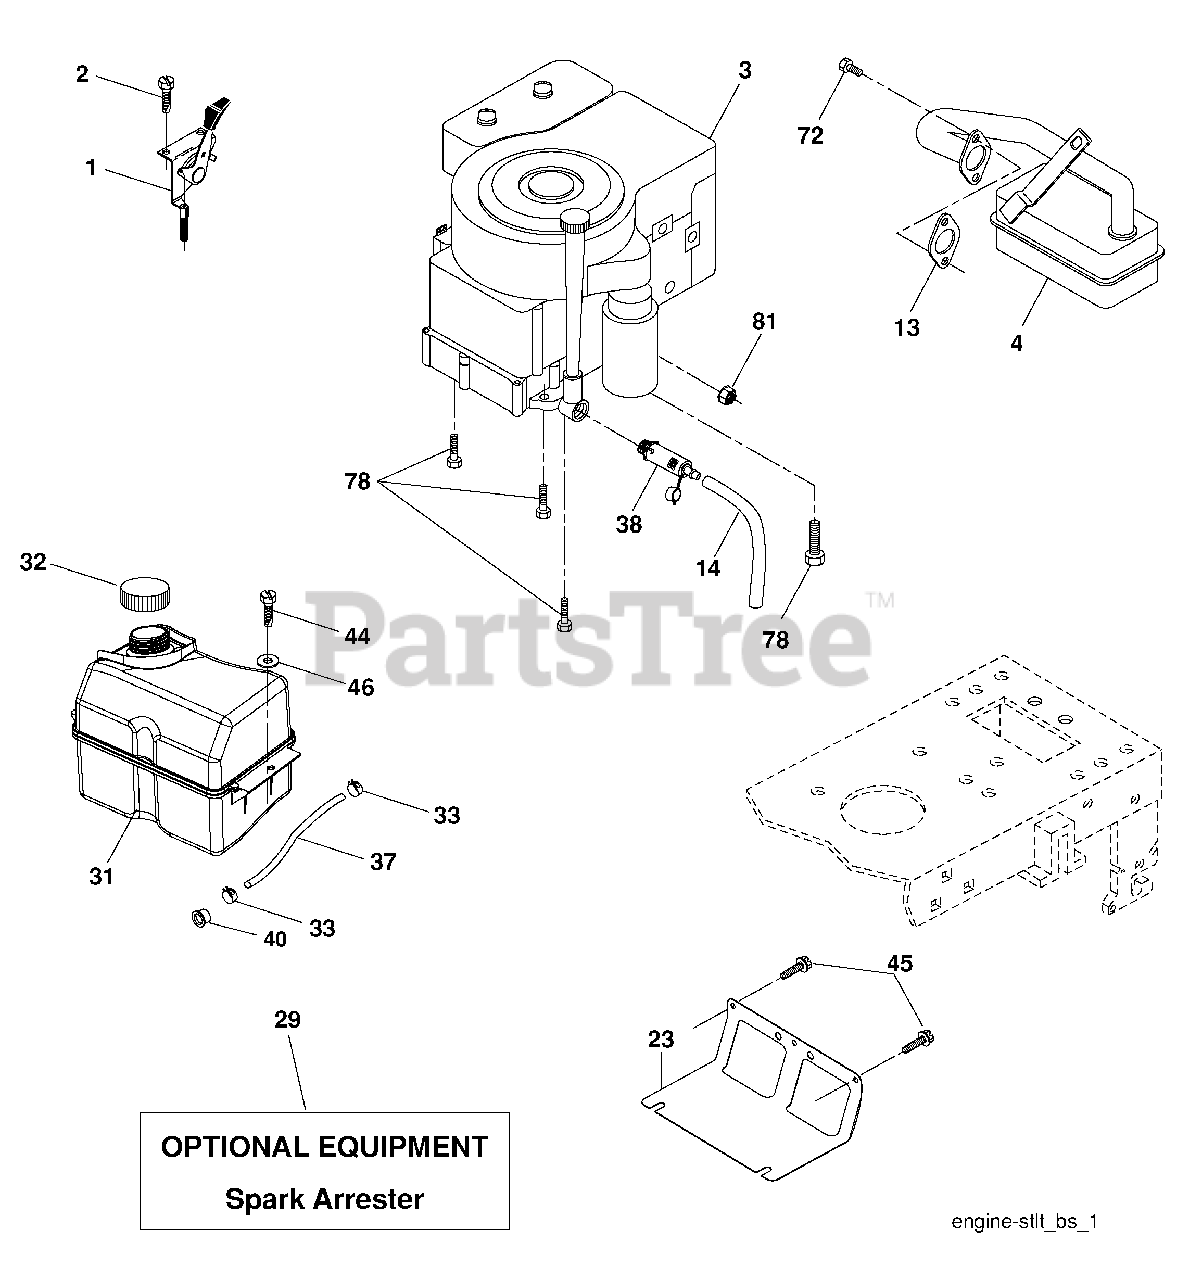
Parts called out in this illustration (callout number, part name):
1	Control Th/ch Flag
2	Screw Hex Thd Cut 1/4-20 x 1/2
4	Muffler Exhaust B&S
13	Gasket Eng 1 313 Id Tin Plated
14	Tube Drain Oil Easy
23	Shield BRN/DBR Guard
29	Kit Spark Arrestor (Flat Scrn)
31	Tank Fuel Front
32	Cap Asm Fuel
33	Clamp Hose
37	Line Fuel 20"
38	Plug Drain Oil
40	Bushing Snap Nyl Blk Fuel Line
44	Screw Thdrol 1/4-20 x 3/4
45	Screw Hex Wsh Thdrol 3/8-16
46	Washer 9/32 x 7/8 x 16 Ga.
72	Screw Socket Head 5/16-18 x 3/4
78	Screw 3/8-16 x 1-1/4
81	Nut Keps Hex 1/4-20 unc
